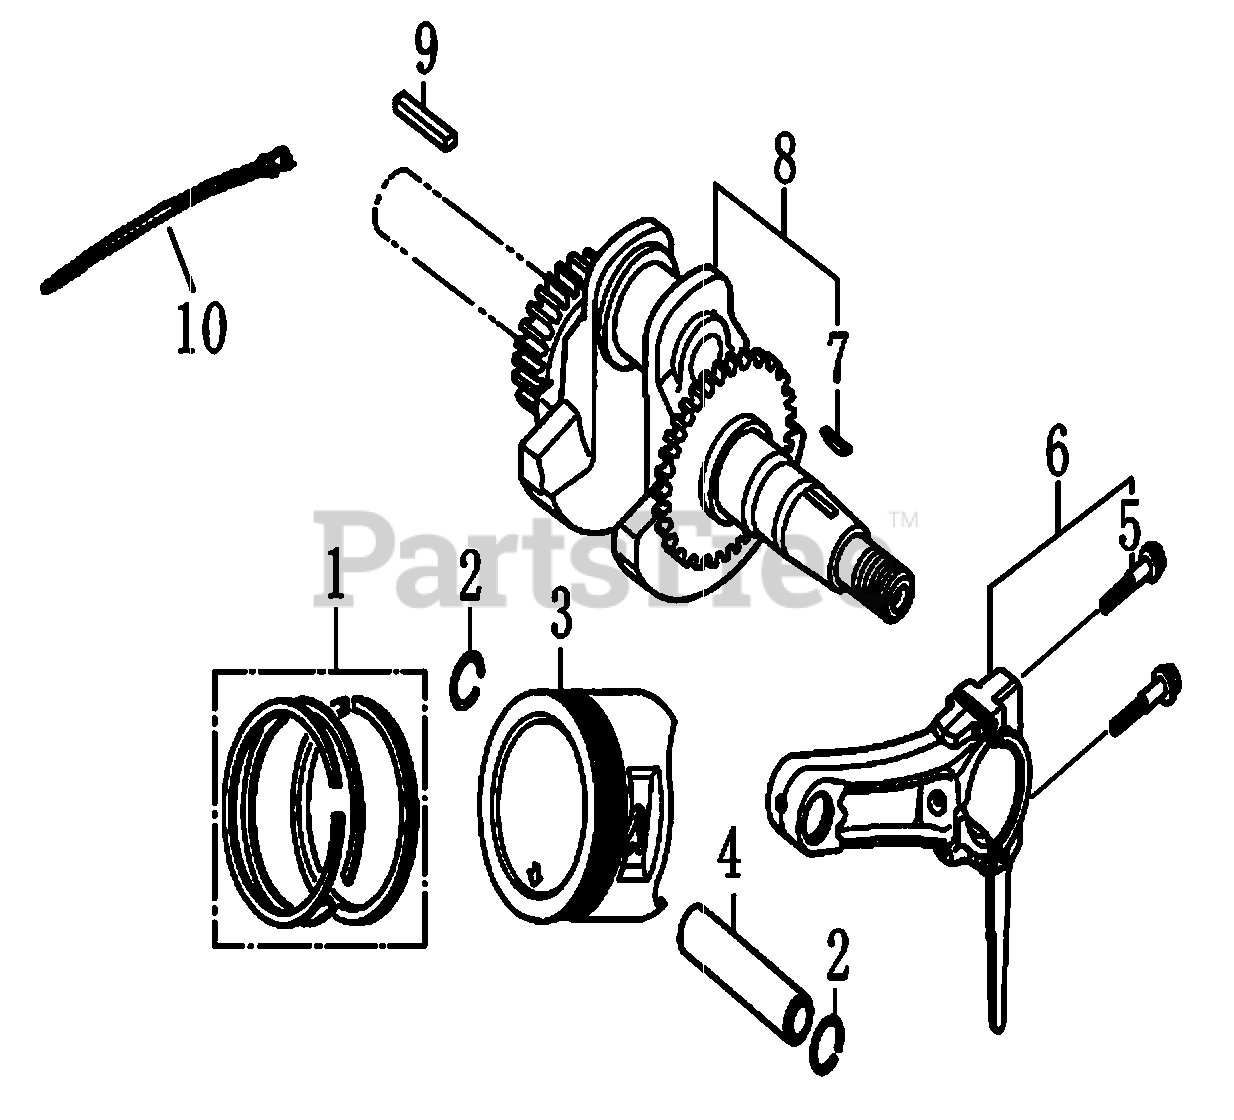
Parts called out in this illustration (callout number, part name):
2	CLIP, PISTON PIN
4	PIN, PISTON
5	BOLT, CONNECTING ROD
6	ROD ASSY., CONNECTING
8	CRANKSHAFT COMP
10	TIE WRAP UL 7.4"X .19" BLK
